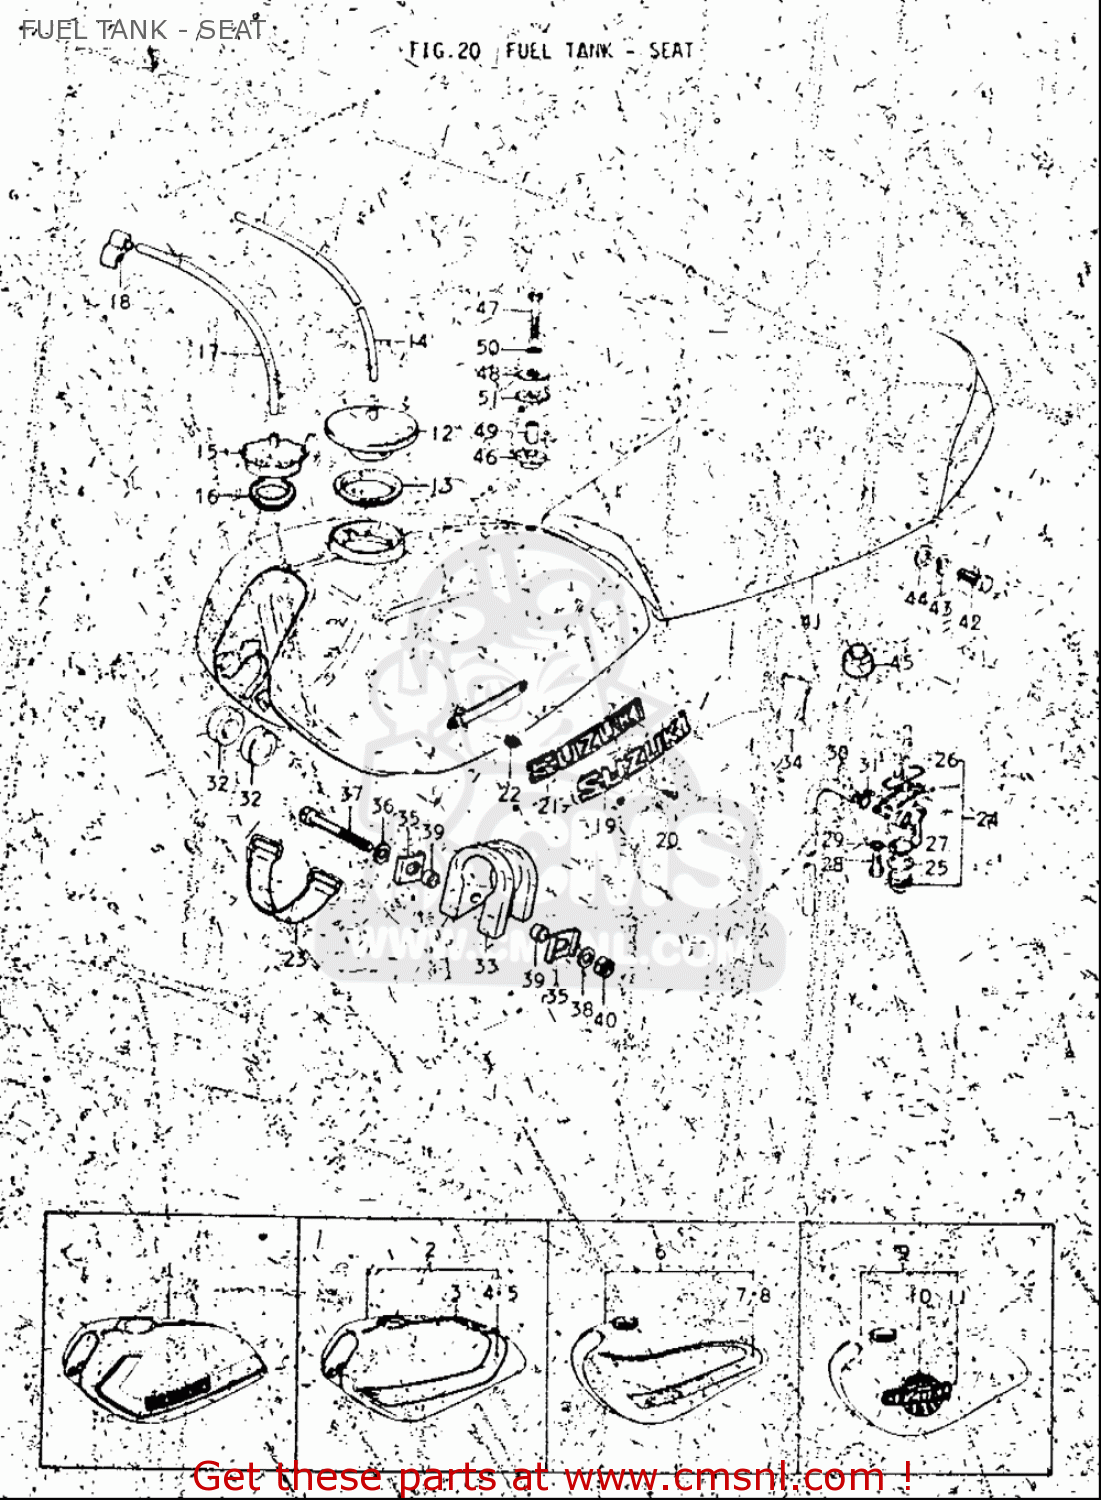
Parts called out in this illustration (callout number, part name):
14	HOSE(5X8.2X2000)
15	CAP ASSY,FUEL TANK FILLER
17	HOSE(5X8.2X600)
18	CLAMP,FUEL TANK BREATHER HOSE
20	SCREW
22	NUT
23	BAND
24	COCK ASSY,FUEL
25	GASKET,FILTER (NAS)
26	FILTER SET,FUEL COCK
27	NET,STRAINER
28	SCREW
29	GASKET(5.8X13X1.2) (NAS)
30	HOSE(5X9X600)
31	CLIP
32	CUSHION
37	BOLT
38	WASHER
39	SPACER(6.1X8X5.2)
40	NUT
42	BOLT
43	WASHER,LOCK
44	WASHER
45	CUSHION
46	CUSHION
47	BOLT
48	WASHER (8.5X30X2.3)
49	SPACER(8.2X12X17)
50	WASHER,LOCK
